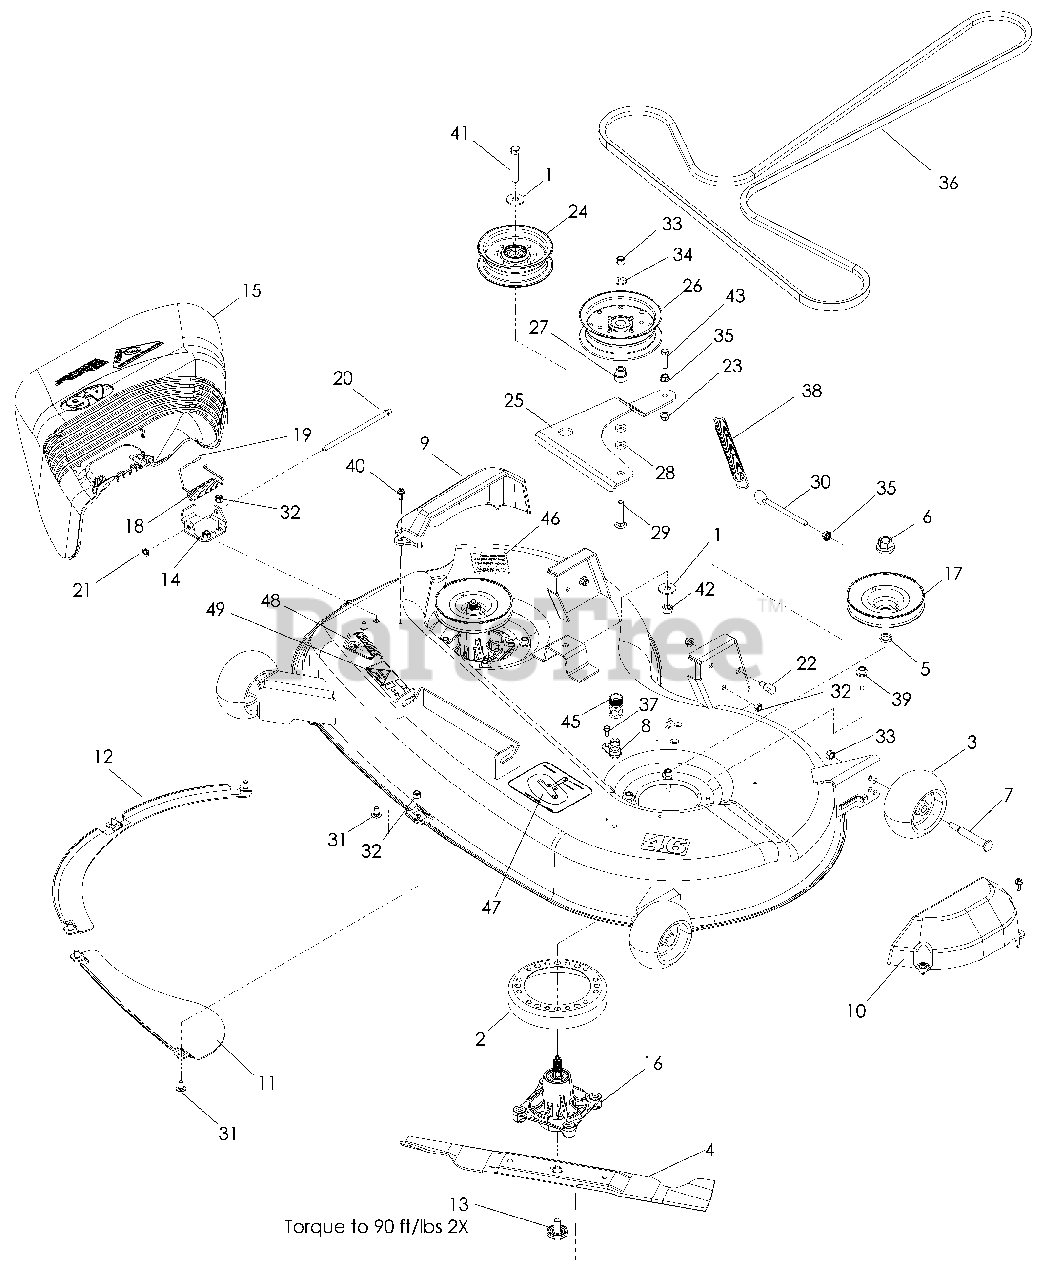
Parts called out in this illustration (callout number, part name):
1	WASHER 7/16 FLAT
2	STRIPPER, ROUND
3	WHEEL, GAUGE
4	BLADE, 46" HI-LIFT
5	WASHER/SPACER
6	NUT 9/16 TOP CNTRLK
7	BOLT ½ x 25/8 SHOULDER
8	PORT, WASHOUT
9	SHIELD, BELT RH
10	SHIELD, BELT LH
11	BAFFLE, FRONT
12	BAFFLE, FRONT RH
13	BOLT WASHER ASSM
14	BRACKET, DEFLECTOR
15	SHIELD, DEFLECTOR
16	HOUSING, CUTTER
17	PULLEY, DECK
18	SPRING, TORSION
19	CAP, SLEEVE
20	ROD, HINGE
21	PUSHNUT
22	STUD, w/ANTI-ROTATE
23	NUT 5/16-18 FLANGE NYLOC
24	PULLEY, IDLER
25	ARM, IDLER
26	PULLEY, IDLER
27	BUSHING, IDLER
28	WASHER 3/8 x ¾
29	RHSNB 3/8-16 x 2
30	EYE BOLT 5/16 x 3½
31	RHSNB 5/16-18 x 5/8
32	NUT 5/16-18 HEX NYLOC
33	NUT 3/8-16 HEX NYLOC
34	WASHER 3/8 SAE FLT
35	NUT 5/16-18 HEX WHIZLK
36	BELT, DECK
37	BOLT ¼-20 x ½ HWST
38	SPRING, DECK BELT
39	SCREW 5/16-18 WSHER HD
40	SCREW ¼-20 x 5/8 THDROLL
41	HCS 7/16-14 x 2½
42	NUT 7/16-14 HEX
43	HCS 5/16-18 x 1¼
44	DECK w/DECALS
45	COUPLING, QUICK CONN
46	DECAL, WARNING
47	DECAL, BELT ROUTING
48	DECAL, WARNING
49	DECAL, SEVERING
